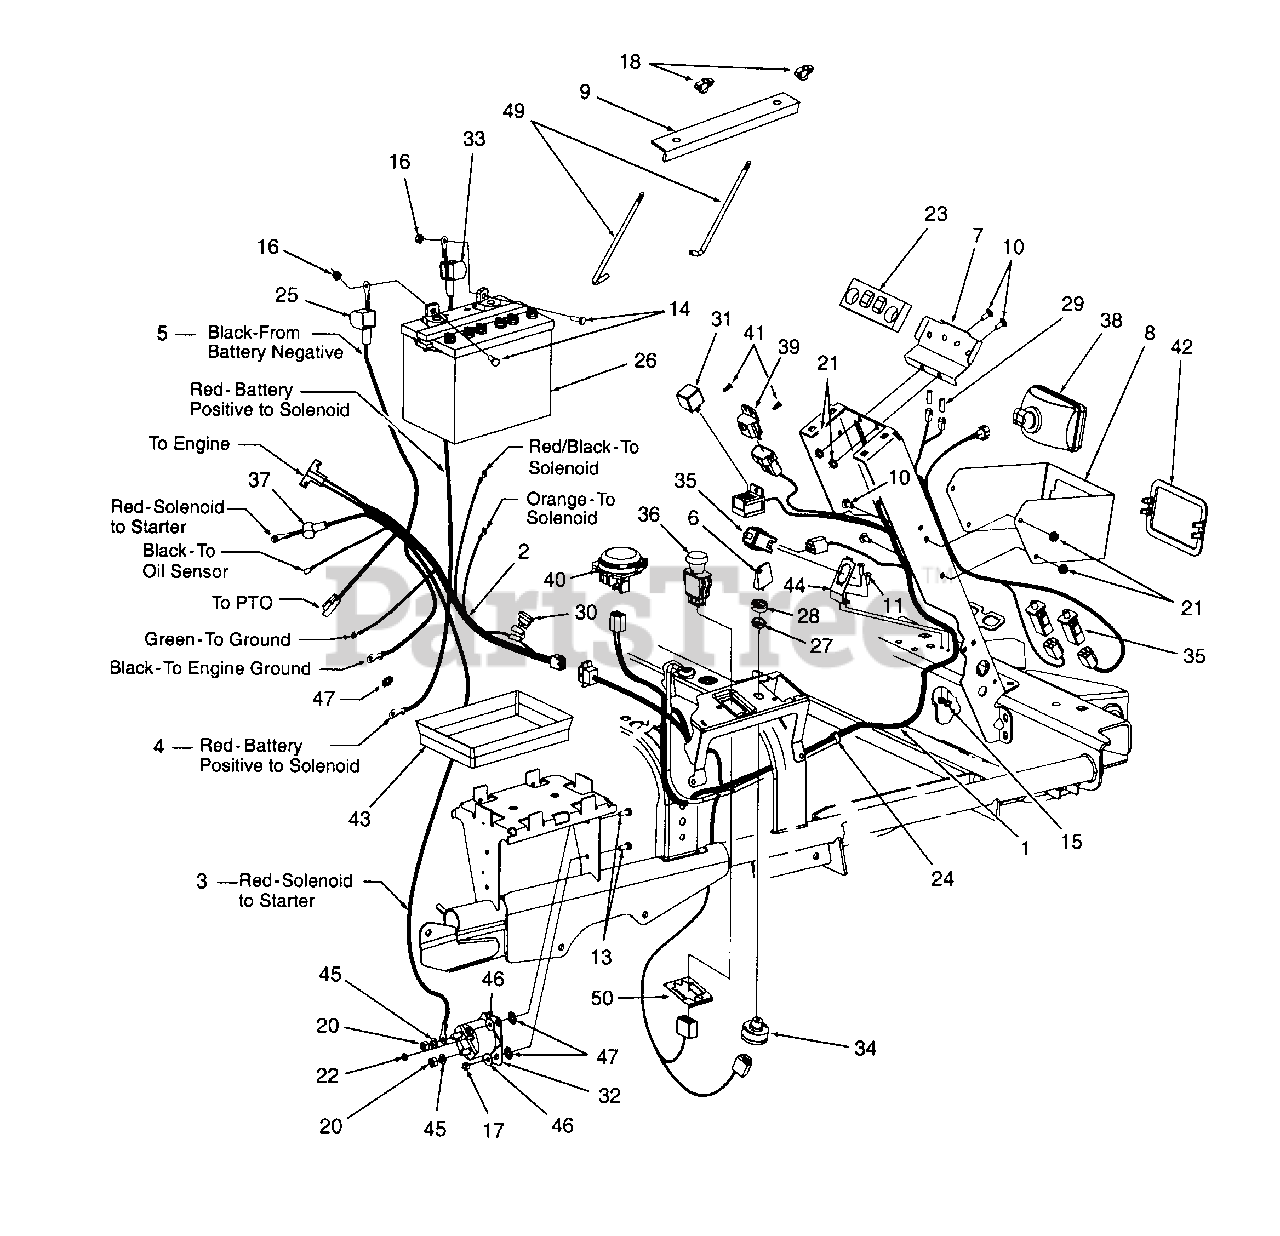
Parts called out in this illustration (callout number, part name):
1	Wire Harness, Main
2	Wire Harness, Engine
3	Battery Cable, Red
4	Battery Cable, Red
5	Battery Cable, Black
6	Key, Ignition
10	Bolt, Carriage, 1/4-20 x .62
11	Screw, Machine, #10-24 x 5/8
13	Screw, Hex Cap, 1/4-20 x .62 GR5
14	Screw, Hex Cap, 1/4-20 x .75 GR5
15	Nut, Hex Insert Lock, #10-24
16	Nut, Hex Sems, 1/4-20
17	Nut, Hex Center Lock, 1/4-20
18	Nut, Nylon Wing, 1/4-20
20	Nut, Hex, 5/16-18
21	Nut, Hex Flange Lock, 1/4-20
22	Nut, Hex Sems, #10-32
23	Foam Protector, Indicator Light
24	Cable Tie
25	Cover, Battery Terminal - Black
27	Nut, Ignition Switch, 5/8-32
28	Cap, Ignition Switch
29	Bulb, Indicator
30	Fuse, Mini, 20Amp
31	Relay
32	Solenoid Switch
33	Cover, Battery Terminal - Red
34	Switch, Ignition
35	Switch, Plunger Safety
36	Switch, PTO
37	Cover, Terminal - Red
38	Headlight Assembly
39	Sensor, Voltage
40	Switch, Seat
41	Retainer, Ratcheet
42	Bezel, Headlight
43	Tray, Battery
44	Spring, Switch Mounting
45	Washer, Lock, 5/16
46	Washer, Bell, .265 x .75 x .062
47	Washer, Int./Ext. Lock, 1/4 ID
49	Rod, Battery Retainer
50	Bracket, PTO Switch Retainer
